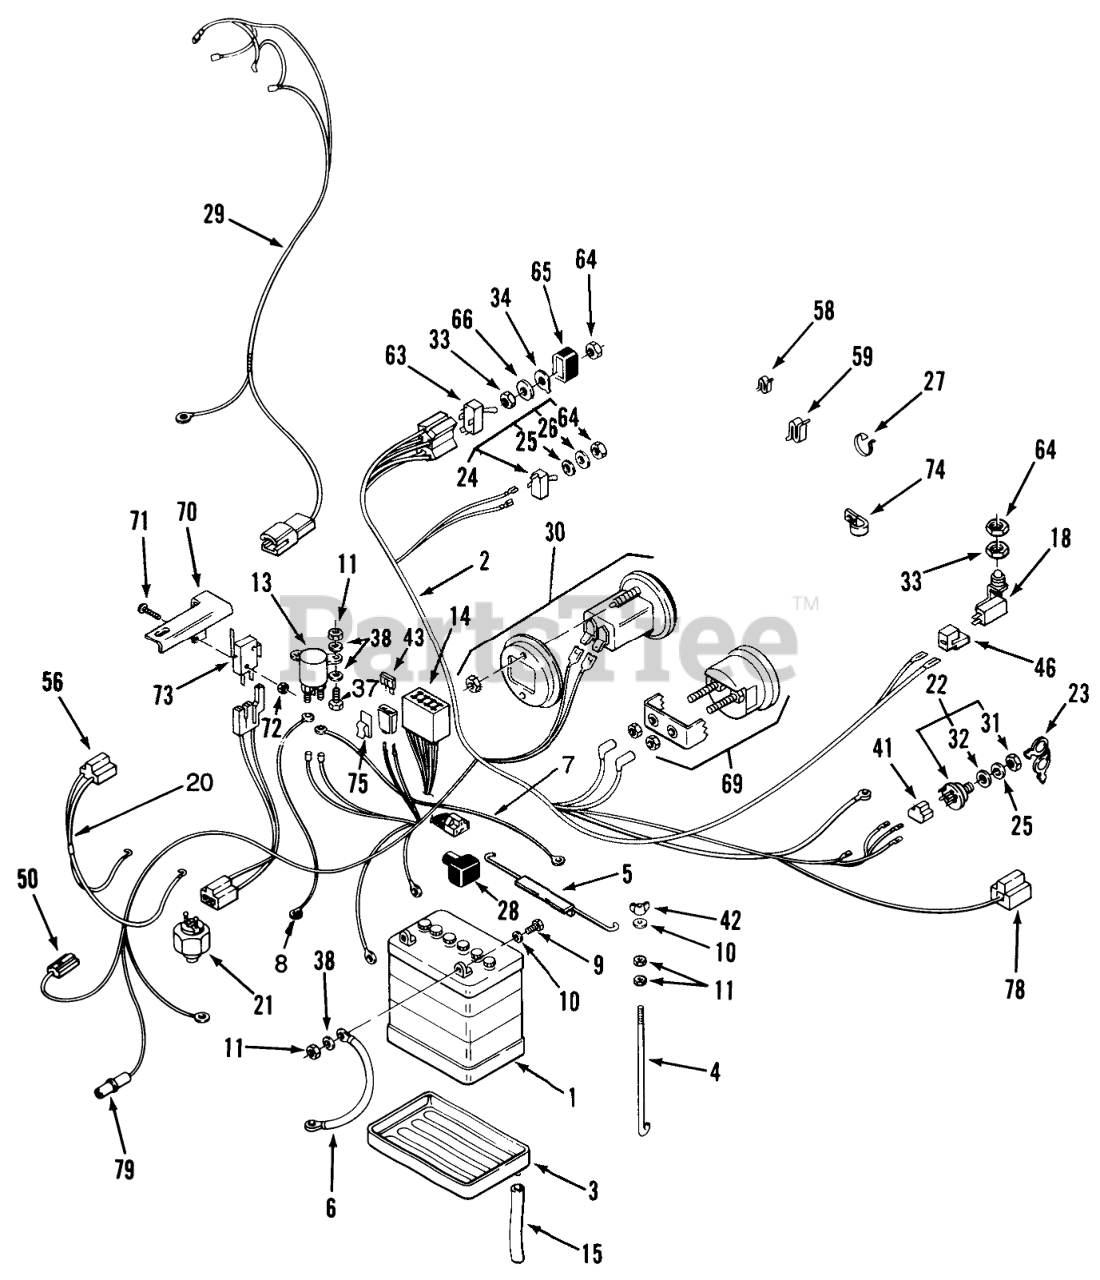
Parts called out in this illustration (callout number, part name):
1	Battery
2	Harness Wire-212-H (Incl. Ref. #14, 41, 46, 78 & 79)
2	MAIN-HARNESS & DIA
3	TRAY-BATTERY
5	HOLDDOWN-BATTERY
6	WIRE -BLACK
7	WIRE - 14" BLACK
8	ASSY WIRE
9	SCREW-HH
10	WASHER-FLAT
11	NUT-HEX
13	Solenoid (Incl. Ref. #11)
14	FUSE-HOLDER 4 WAY
15	TUBE-BATTERY DRAIN
18	Seat Switch
20	ASSY WIRING HARNESS
21	SWITCH (N.C.-TRANS)
22	Switch-Ignition (Incl. Ref. #31-32)
23	Ignition Key
24	Switch-Light (212-5 & 212H) (Incl. Ref. #25, 26 & 64)
25	Washer
26	Washer
27	PLASTIC TIE
28	Boot
29	HARNESS-HEADLIGHT
30	Hourmeter (Incl. 114017 Bracket, 915962 Keps Nut (2) & 5924 Nut (2)
32	LOCKWASHER
33	Nut-Special
34	TAB-WASHER
37	Screw
38	WASHER-LOCK
41	CONNECTOR-5 WAY-SERV
42	Nut
43	FUSE-BLADE, 15 AMP
43	FUSE-BLADE, 25 AMP
43	FUSE-BLADE, 30 AMP
46	CONNECTOR BODY
50	CONNECTOR BODY ELECT
56	CONNECTOR BODY B
57	TERMINAL-TAB RCPT
58	CLIP
59	SPEED CLIP
63	SWITCH-TOGGLE DPDT
65	COVER-PTO SWITCH
66	WASHER
69	Voltmeter (Incl. 109650 Clamp & 5924 #10-32 Nut, 2 Req.)
70	BRKT-TRANS NEUT S R
71	Screw
72	NUT HEX 4-40 ELAST
73	SWITCH
74	CLAMP
78	CONNECTOR 5 WAY
79	Connector-Socket
